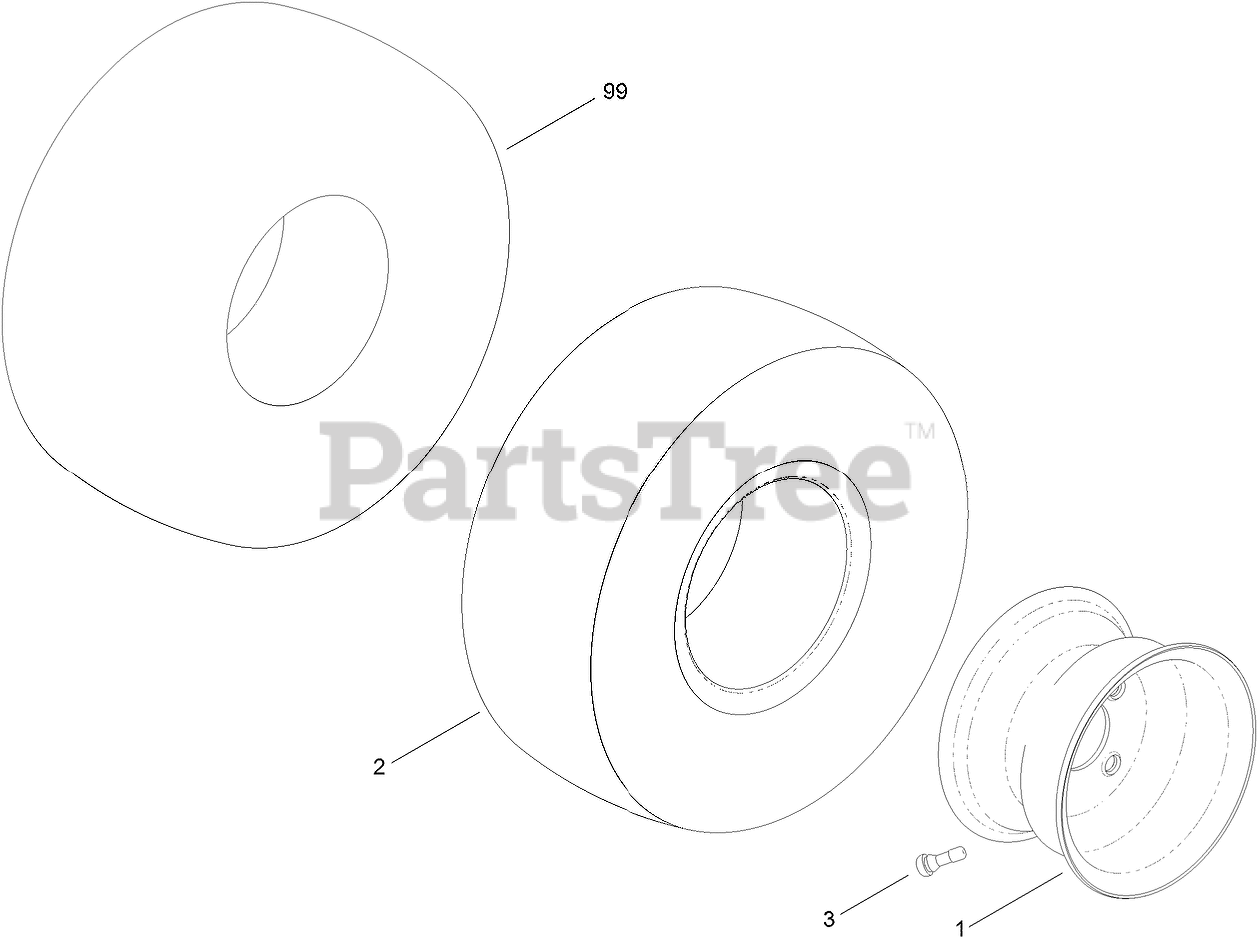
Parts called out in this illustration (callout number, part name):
2	TIRE (Kenda)
3	STEM-VALVE
99	TUBE-TIRE
